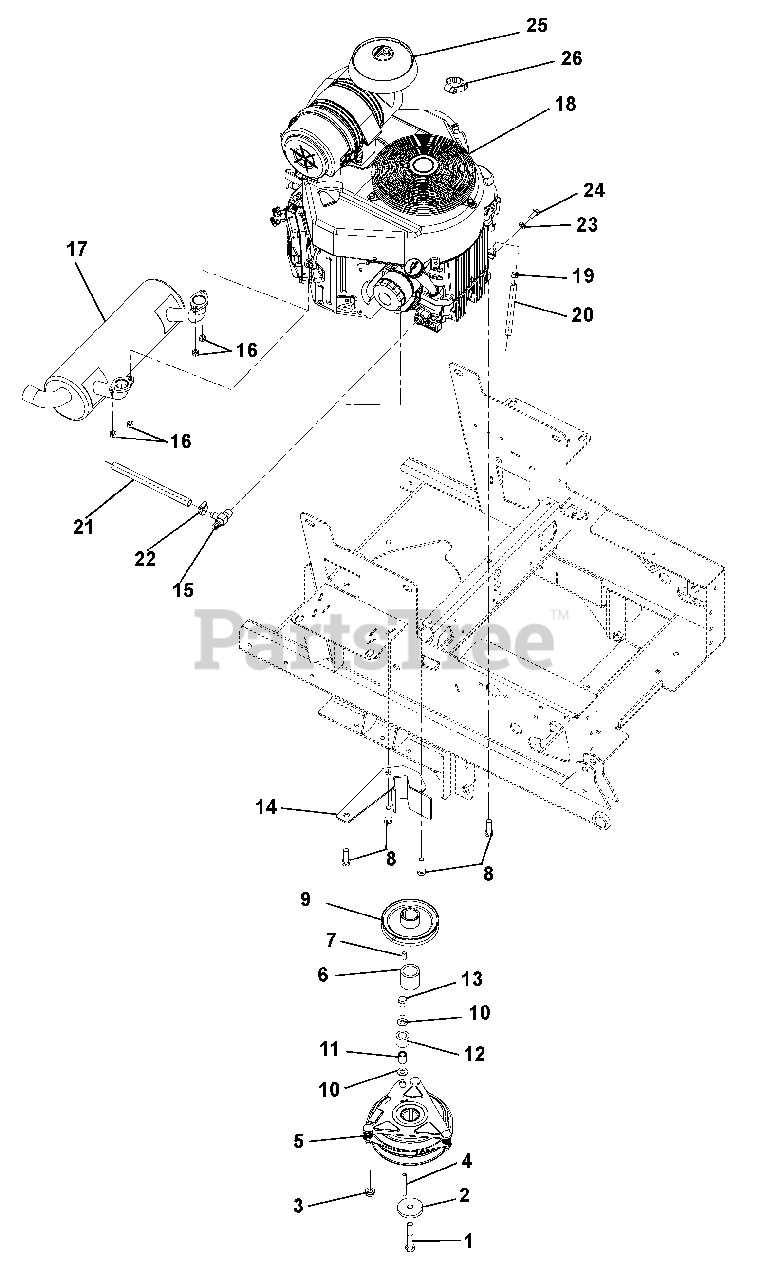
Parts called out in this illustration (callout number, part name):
1	Bolt, Hex .44-20 x 2.50 Grade 5
2	Washer, Flat-Steel .469 x 2.00 x .25
3	Nut, Locking-Top-Flange .38-16
4	Key .25 x .25 x 2.25
5	Clutch, Ogura GT2.5-FE02
6	Spacer, 1.125 x 1.50 x 1.40
7	Key, Square .25 x .625 x .25 SAE 8630 OR SAE 1035
8	Bolt, Hex .38-16 x 1.25 FTH Grade 5
9	Sheave, 4.831 x 1.127
10	Washer, Flat-Steel .406 x .812 x .065
11	Bushing, Sleeve .407 x .625 x .813 Steel
12	Bumper, Rubber .62 x 1.0 x .88 LG Engine
13	Bolt, Hex .38-16 x 1.50 Grade 5
14	100I Clutch Stop Weldment
15	Drain, .50 Oil
16	Nut, Locking-Top M8-1.25
17	Muffler, 26HP Kawasaki Veritcal
18	Engine, Kawasaki FX691 (24HP) (062, 063)
19	Clamp, Fuel Line
20	Hose, .25 Low-PERM Bulk Gas
21	Tube, Oil Drain 8" Clear Vinyl
22	Clamp, .88 Diameter Hose
23	Washer, Locking .31 x .078 Regular
24	Bolt, Hex M8-1.25 x 20
25	Cap, Air Cleaner Rain
26	Clamp, Hose 2.75 Dia. Worm
NS	Lead, Starter Solenoid
NS	Air Filter Element, Outer Primary
NS	Air Filter Element, Inner Safety
NS	Filter, Oil- Kawasaki # 49065-2078
NS	Plug, Spark- Kawasaki P/N 92070-7004
NS	Filter, Fuel- Kawasaki #49019-7001
